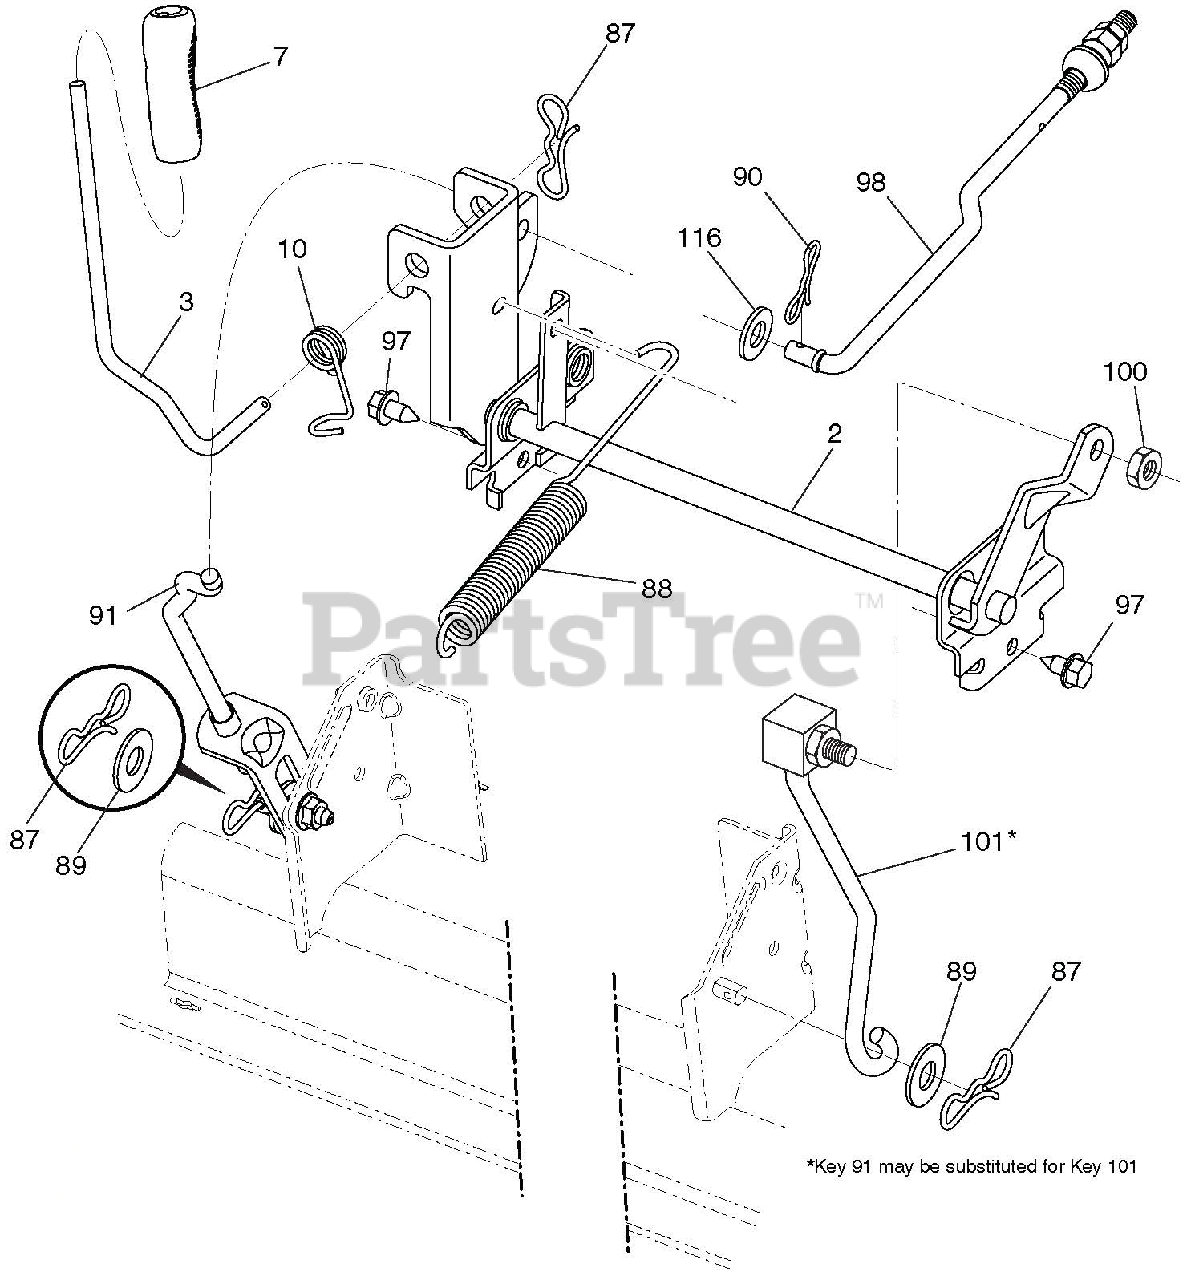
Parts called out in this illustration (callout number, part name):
2	SHAFT ASM., LIFT
3	LEVER.LIFT.HANDLE.LT
7	GRIP LEVER 5625 LD BLACK 428
10	SPRING.TORSION.HANDLE.LIFT
87	PIN.COTTER.7/16.BOW TIE LOCK
88	SPRING.LIFT ASSIST
89	WASHER.CLEAR ZINC
90	PIN.COTTER.5/16.BOW TIE LOCK
91	LINK ASM.LIFT.LH.REAR
97	SCREW.HEXWSH THDR3/8-16X3/4.BL
98	LINK ASM.SUSP.FRONT.MWR.11
100	NUT.CENTERLOCK.3/8-16 UNC.
101	LINK ASM.LIFT.FIXED.38/42/46"
116	WASHER 15/32 X 15/16 X 16 GA.
